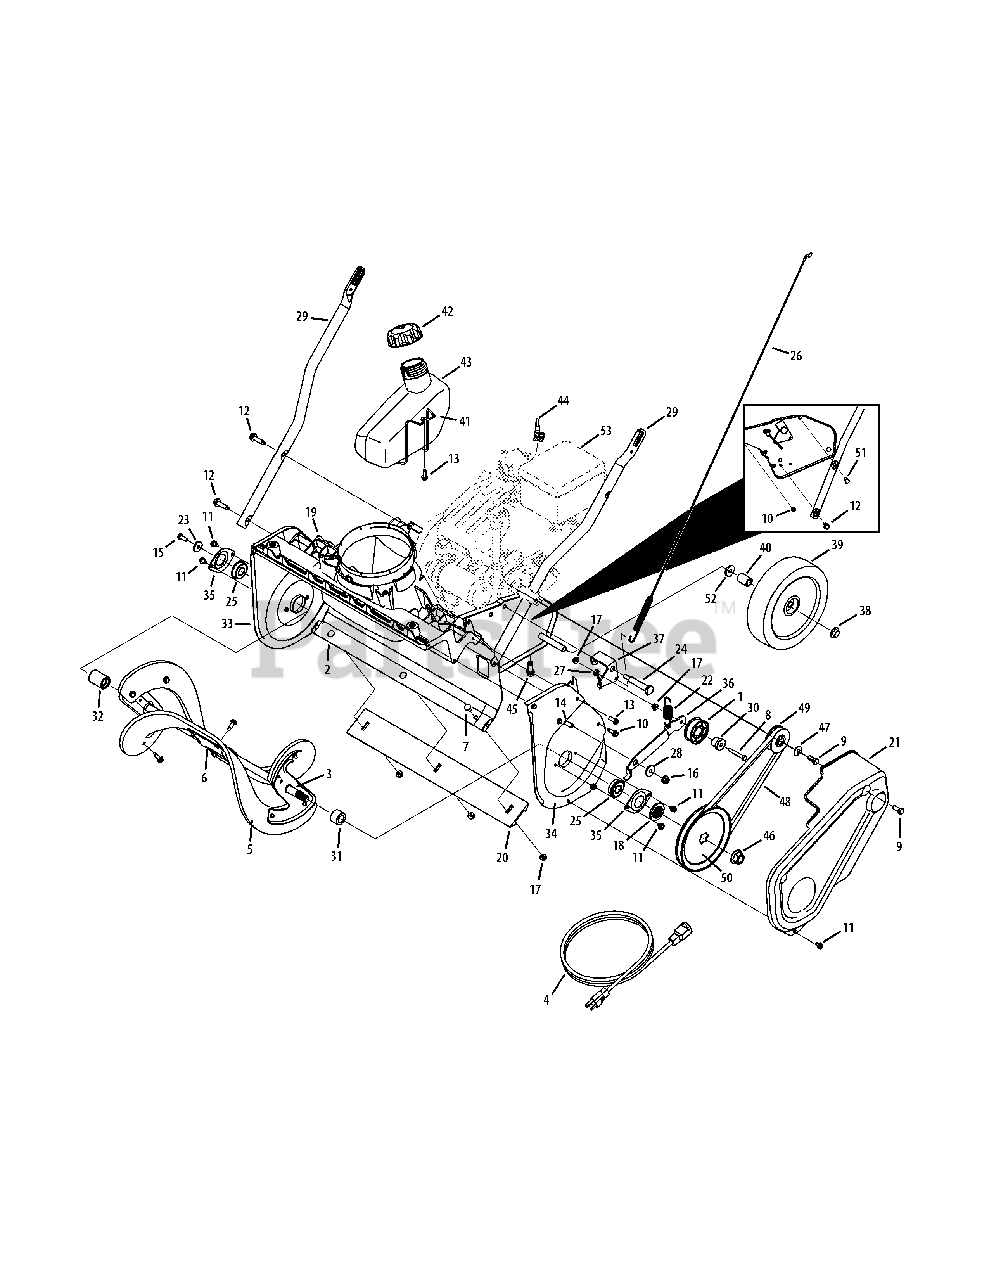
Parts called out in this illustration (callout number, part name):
1	Idler Pulley Assembly
2	Frame
3	Auger Assembly Mount
4	3-Prong Extension Cord
5	Auger Replacement Kit
7	Carriage Screw, 1/4-20 x .62
8	Hex Screw, 1/4-20 x 1.757
9	Hex Lock Screw, 5/16-24 x .750
10	Hex Washer Screw, 1/4-20 x .750
11	Hex Washer Screw, 1/4-20 x .375
12	Hex Washer Screw, 5/16-18 x 1.250
13	Hex Washer Screw, 1/4-15 x .750
14	Hex Screw, 5/16-18 x .75
15	Hex Lock Screw, 1/4-20 x .750
16	Flange Lock Nut, 5/16-18
17	Flange Lock Nut, 1/4-20
18	Pulley Hub
19	Chute Adapter
20	Shave Plate
21	Belt Cover
22	Extension Spring, .70 x 3.035
23	Flat Washer, .265 x .938 x .120
24	Shoulder Bolt, 5/16-24 x .496 x 2.18
25	Ball Bearing, .625 x 37 x 12
26	Clutch Cable
27	Drive Cable Wire Support
28	Shoulder Spacer
30	Shoulder Spacer, .260 x .785 x .538
31	LH Auger Spacer
32	RH Auger Spacer
33	RH Auger Plate
34	LH Auger Plate
36	Idler Bracket
37	Cable Idler Bracket
38	Push Cap, 1/2
40	Sleeve Spacer, .525 x .78 x 1.00
41	Gas Tank Wire Support
42	Fuel Cap
43	Fuel Tank
44	Choke Extension Lever
45	Hex Washer Screw, 3/8-16 x 1.000
46	Flange Nut, 9/16-18
47	Flat Washer, .343 x .88 x .062
48	Belt, .500 x 35.06
49	Pulley Half, .625 x 2.25
50	Pulley, 1/2 x 6.00
51	Hex Screw, 5/16-24 x 1.25
52	Flat Washer, .531 x 1.062 x .134
53	Replacement Engine
